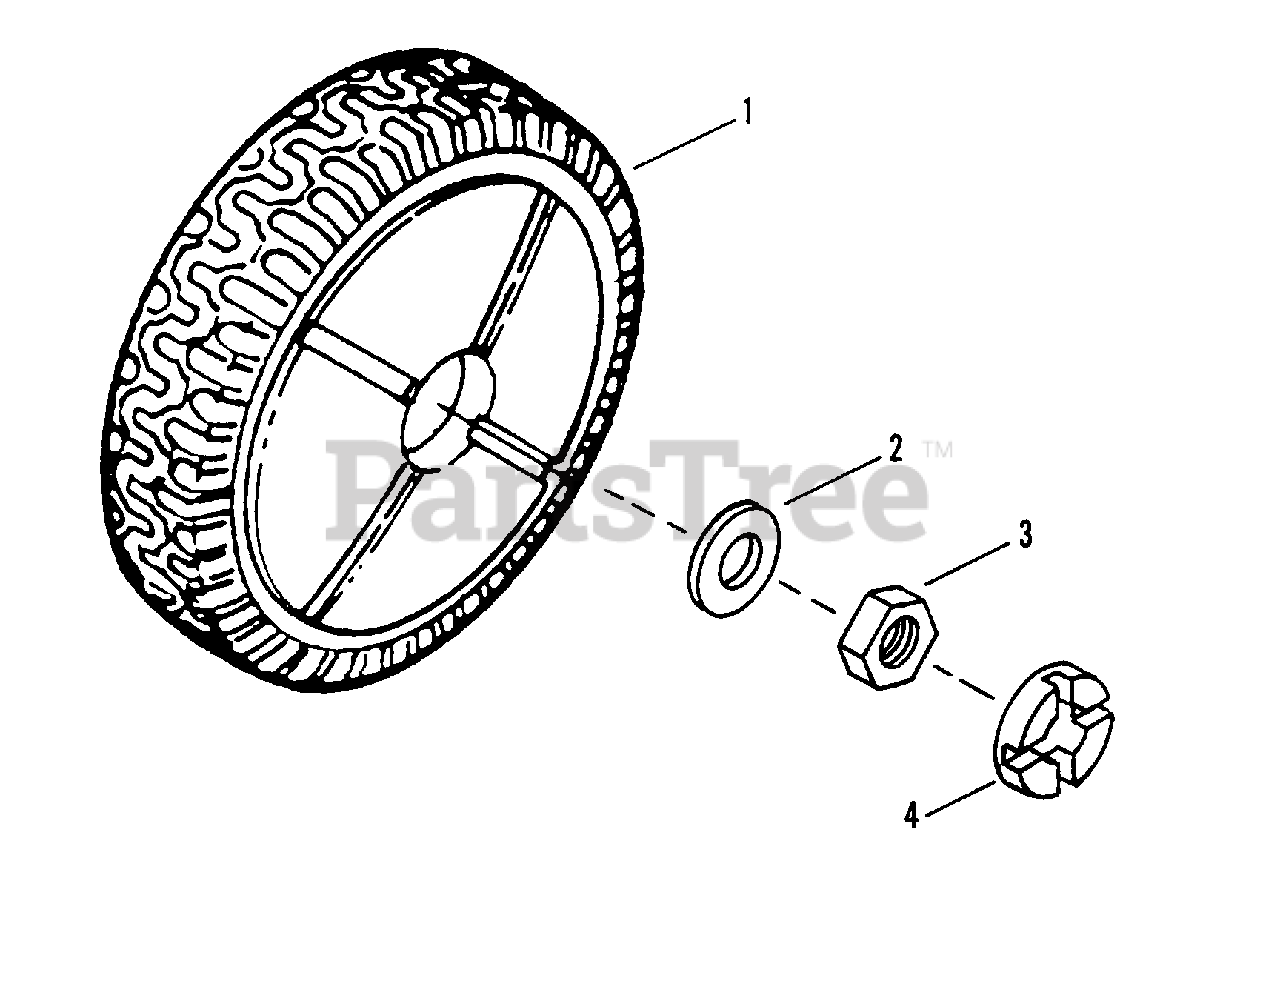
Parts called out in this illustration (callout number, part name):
1	WHEEL, 9 x 2.00, Steel
2	WASHER, 7/16" ID x 1" OD SAE
3	NUT, 7/16-20 Hex (Thin)
4	PLUG, Wheel
